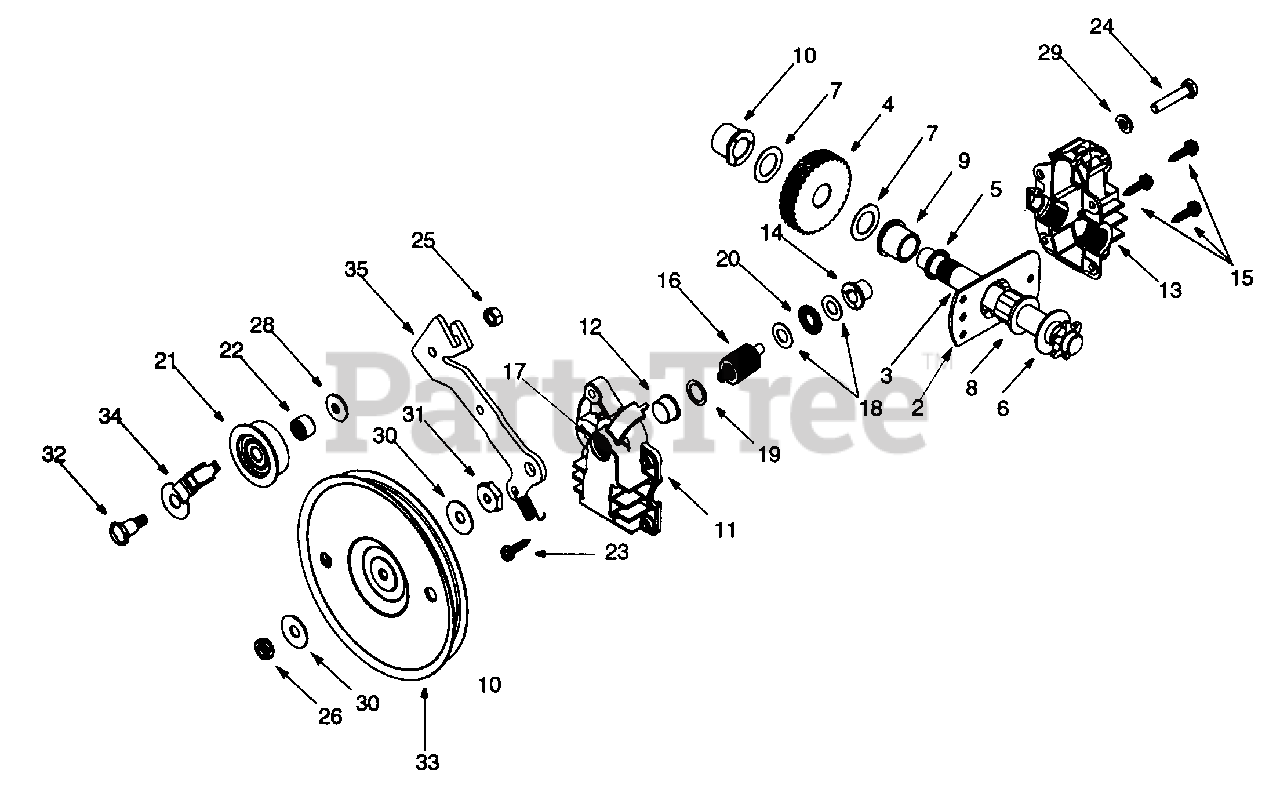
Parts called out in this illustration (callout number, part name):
1	Transmission Assembly Complete
2	Hex Bearing Cup
3	Output Shaft 6T Sprocket
4	Helical 34T Gear
5	Oil Seal
6	Flat Washer .64 ID x 1.24 OD
7	Flat Washer 5/8 x 1.0
8	Hex Flange Bearing .631 ID
9	Flange Bearing .629 ID
10	Flange Bearing .566 ID
11	Lower Housing
12	Flange Bearing .503 ID
13	Upper Housing
14	Flange Bearing .378 ID
15	Hex Washer Screw #10-16 x .75
16	Pinion Shaft 107
17	Oil Seal
18	Thrust Washer .382 ID x .684 OD
19	Flat Washer .504 ID x .70 OD
20	Thrust Bearing .375 ID x .812 OD
21	Pulley Ass'y Idler w/ Bearing
22	Needle Bearing .375 ID x .375 OD
23	Hex Screw #10-16 x .75
24	Hex Cap Screw 1/4-20 x 1.25
25	Hex Nut 1/4-28
26	Hex Jam Nut 5/16-24 LH Thd
27	Extension Spring 1.12 Lg
28	Bell Washer .265 ID x .75 OD
29	Lock Washer 1/4
30	Bell Washer .325 ID x .930 OD
31	Shoulder Spacer .375 ID x .165 OD
32	Shoulder Bolt 1/4-28 x .375
33	Flat Pulley 5.06 Dia
34	Belt Keeper
35	Idler Bracket
